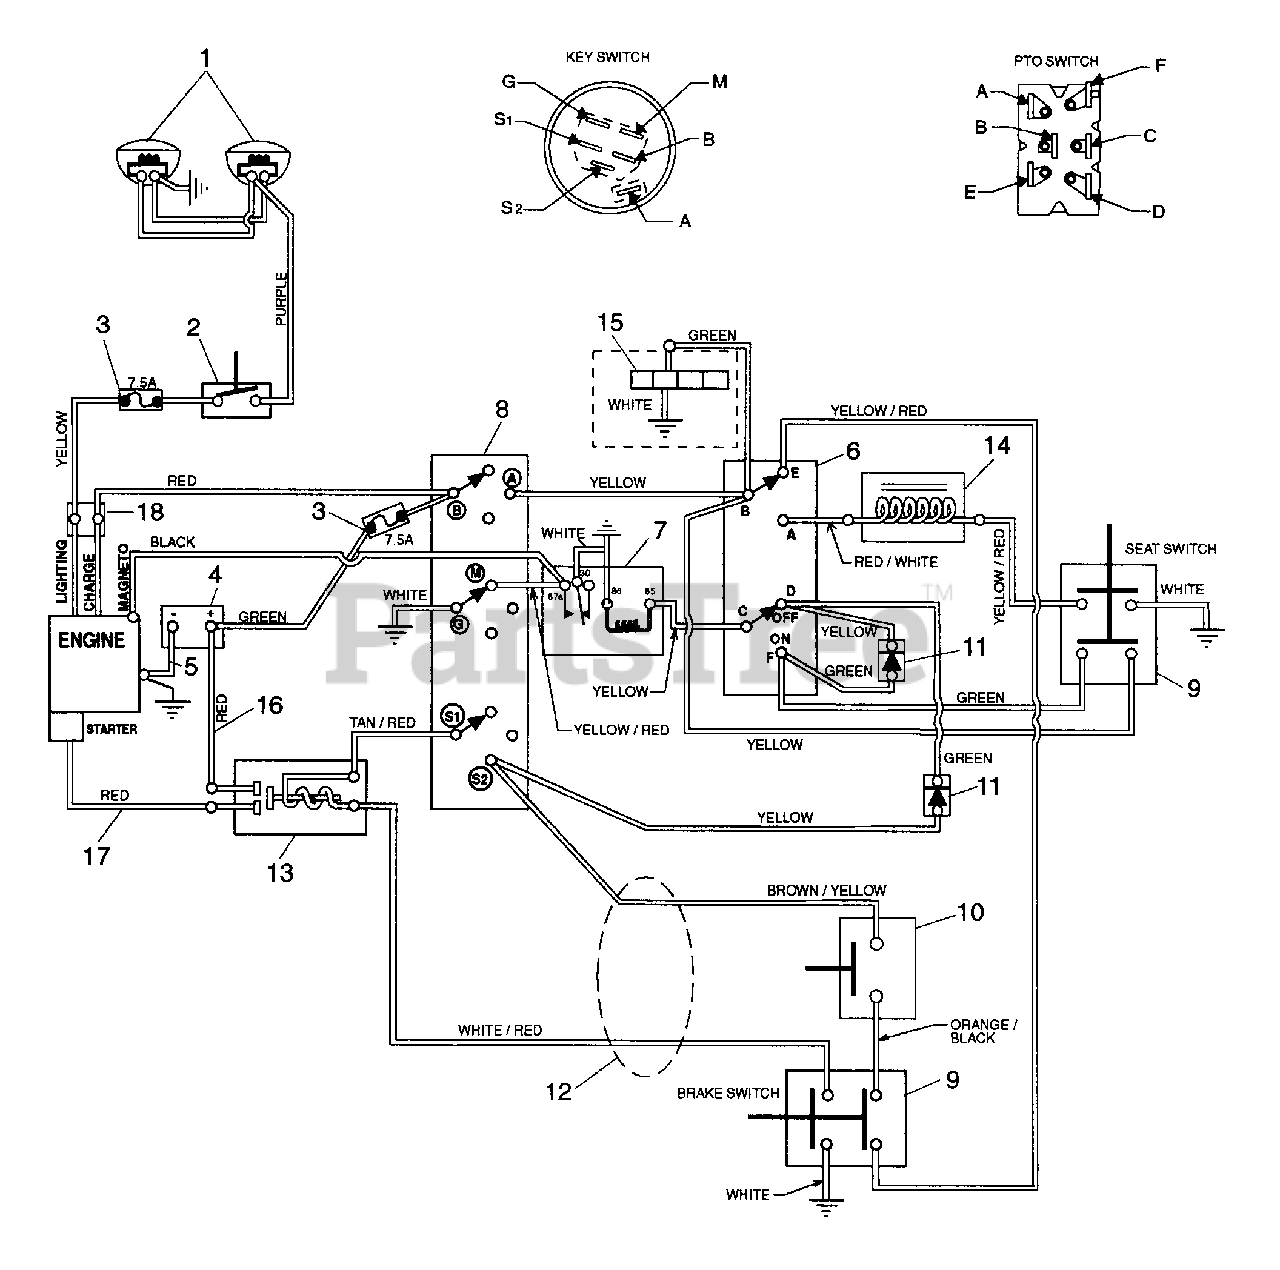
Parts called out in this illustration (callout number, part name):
1	HEADLIGHT- L.H.
1	HEADLIGHT- R.H.
2	LIGHT SWITCH
3	7.5 Amp Fuse
4	BATTERY W/ TUBE
5	GROUND CABLE .31X22.00X.31
6	SWITCH ASSEMBLY- PTO
7	RELAY
8	KEY SWITCH
9	SWITCH- DOUBLE POLE N.O./N.O.
10	SWITCH-NEUTRAL START N.O.
11	MOLDED DIODE PLUG 1 AMP
12	WIRE HARNESS- YT120G/LT12
13	SOLENOID
14	ELECTRIC CLUTCH/BRAKE(1.8AMP)
15	HOURMETER
16	START CABLE 22"
17	STARTER CABLE 13"
18	WIRE HARNESS ADAPTER
